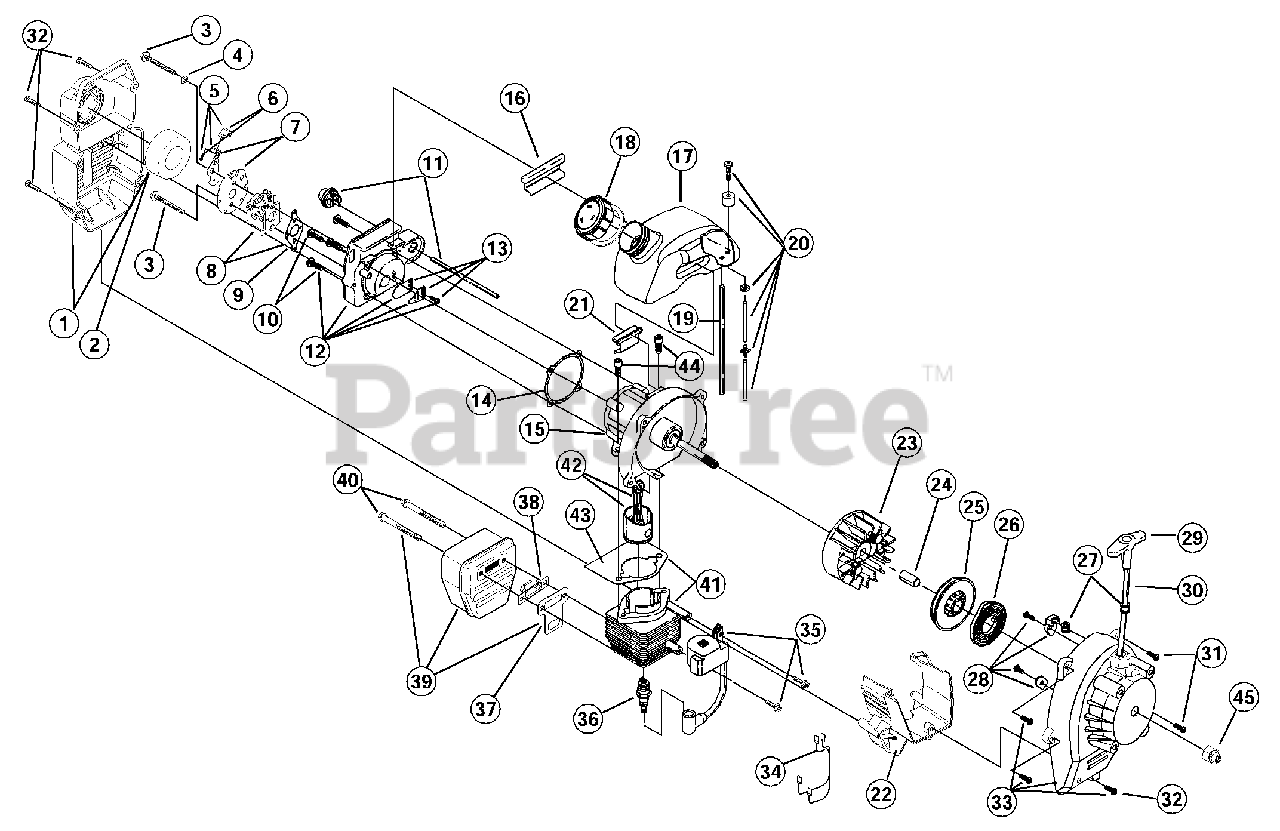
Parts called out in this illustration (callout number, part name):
1	Air Cleaner/Muffler Cover Assembly
2	Air Cleaner Filter
3	Carburetor Mounting Screw
4	Wavey Washer
5	Choke Lever Assembly
6	Choke Knob and Screw
7	Choke Lever and Plate
8	Carburetor Assembly
9	Carburetor Gasket
10	Carb Mount Screw
11	Primer and Hose Assembly
12	Carb Mount Assembly
13	Reed Assembly
14	Carburetor Mount Gasket
15	Crank Case Service Assembly
16	Rear Mounting Pad
17	Fuel Tank Assembly
18	Fuel Cap Assembly
19	Fuel Return Line
20	Fuel Line Assembly
21	Front Mounting Pad
22	Shroud Extension
23	Flywheel Assembly
25	Recoil Pulley Assembly
26	Recoil Spring
27	Rope Guide
28	Pulley Retainer Assembly
29	Pull Handle
31	Housing Screw
32	Cover Screw
33	Starter Housing Assembly
34	Wire Lead Assembly
35	Module Assembly
36	Spark Plug
37	Exhaust Gasket
38	Spark Arrestor Screen
39	Muffler Assembly
40	Muffler Mounting Bolt Assembly
41	Cylinder Assembly
42	Piston and Rod Assembly
43	Cylinder Gasket
44	Cylinder Bolt
45	Crankshaft Extension
